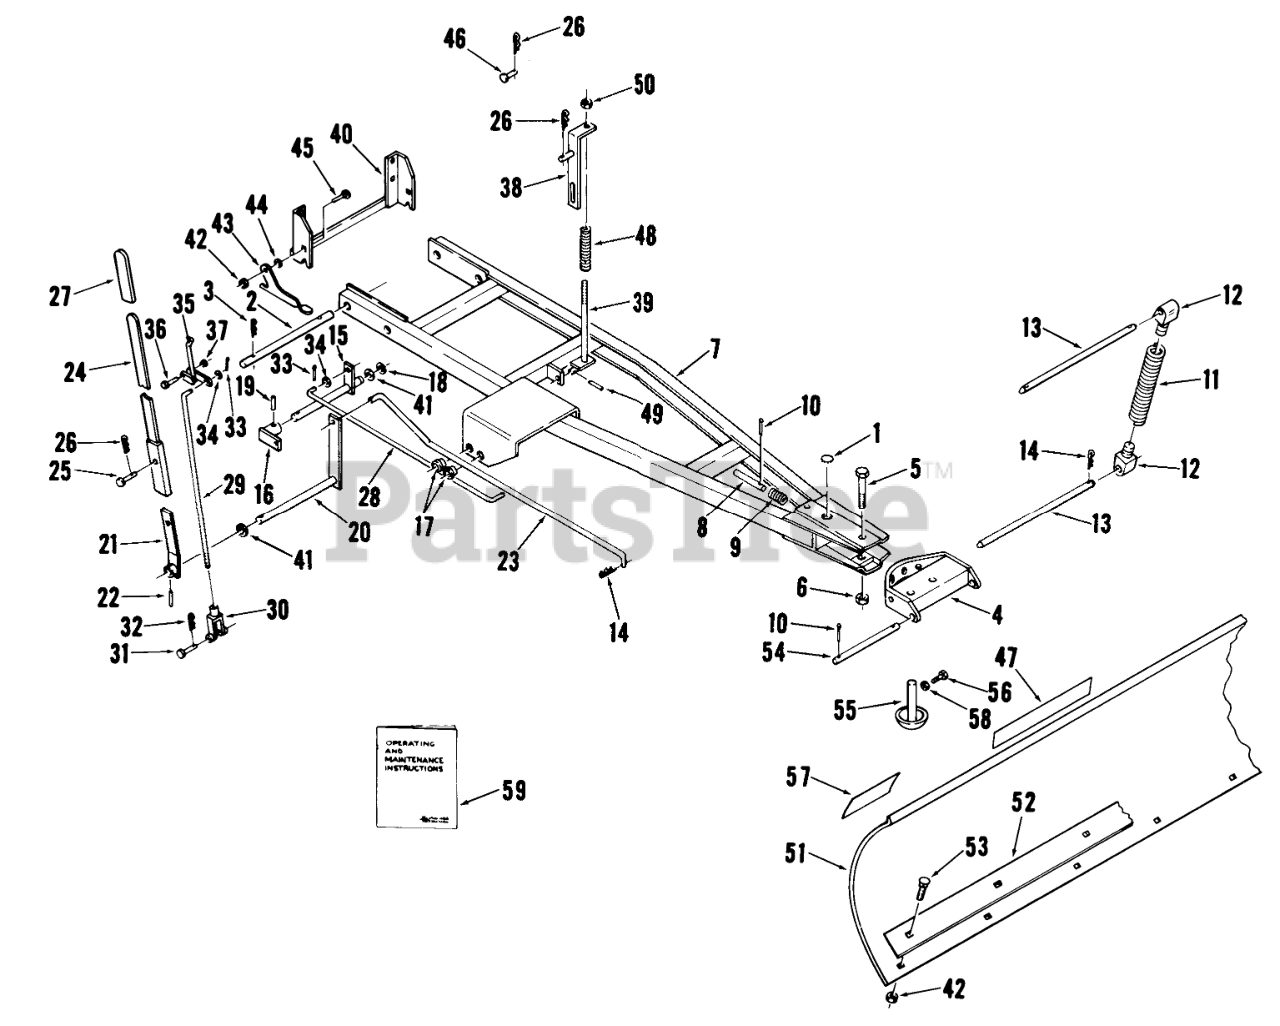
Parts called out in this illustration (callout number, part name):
1	PLUG
2	Mounting Shaft
3	Hairpin
4	Sector and Channel
5	Bolt
6	Nut
7	Frame Assembly
8	Index Pin
9	SPRING-COMPRESSION
11	Spring
12	Lug
13	ROD-TRIP RETURN
14	Hairpin
15	Bushing
16	Sat Collar
17	BUSHING
18	Snap Ring
19	SPIROL PIN 3/8X1 3/4
20	Assembly-Blade Index Arm
21	Assembly-Handle Bar
22	SPIROL PIN 3/8X1 1/2
23	Blade Control Rod
24	HANDLE ASM
25	Pin-Clevis
26	Hairpin Cotter
27	GRIP
28	ROD LOWER INDEX
29	ROD UPPER INDEX
30	YOKE
31	Pin
33	Cotter Pin
35	Assembly Index Lever
36	Bolt
37	Nut
38	Assembly-Lift Bar
39	Assembly Lift Rod
40	Bracket
41	Shim Washer
42	NUT
43	PLATE-LATCHING
44	Washer
45	BOLT
46	Pin
47	DECAL-WHEEL HORSE
48	SPRING
49	Spirol Pin
50	Nut
51	Blade Assembly
52	PLATE-BLADE EDGE
53	Bolt-Carriage
54	ROD-LOWER
55	SKID SHOE ASSY R
56	Screw-Set
57	Caution Decal
58	Nut
59	Operating and Maintenance Instructions
